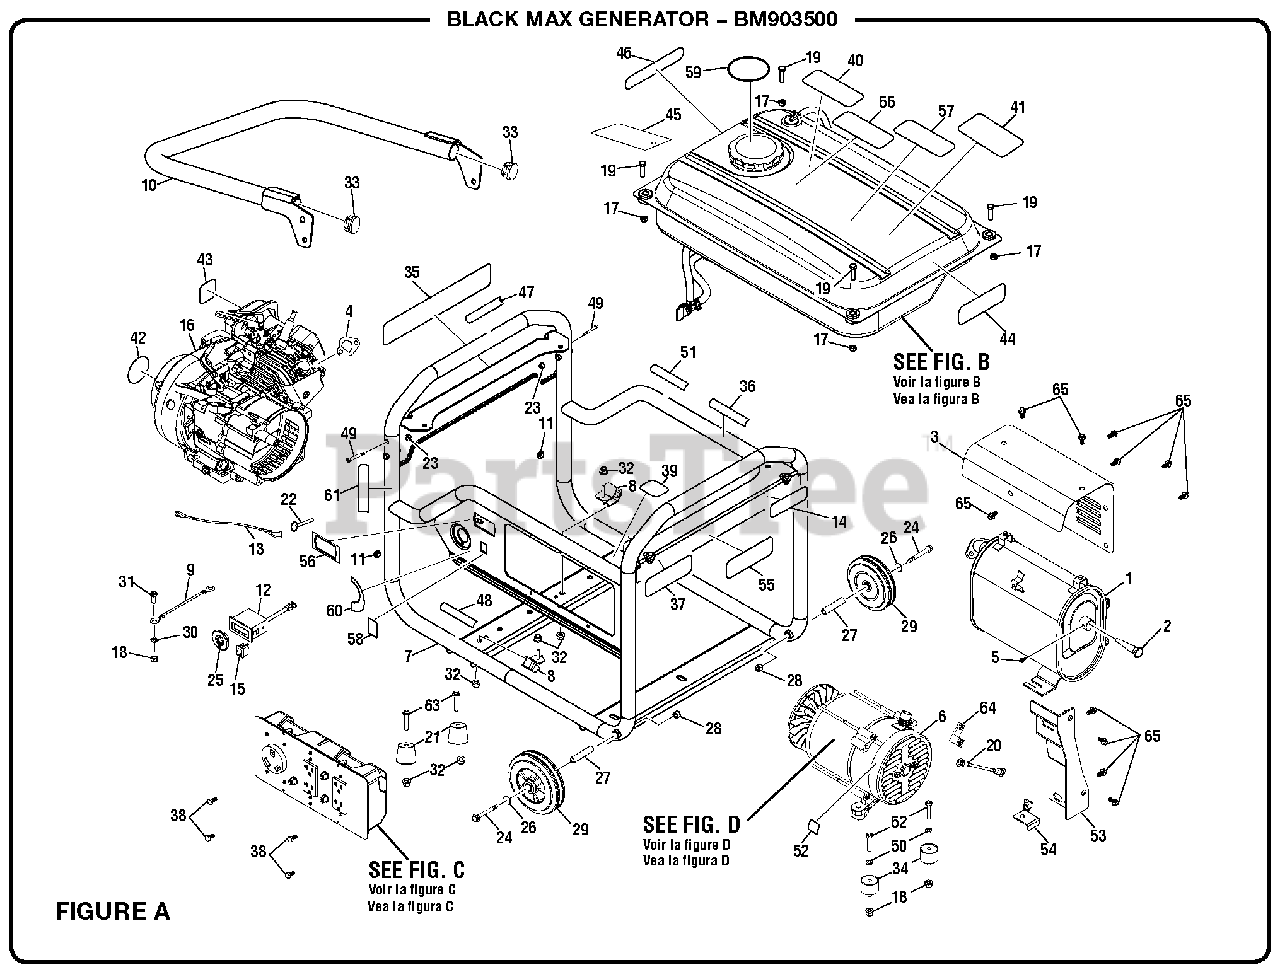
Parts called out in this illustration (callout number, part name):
2	Spark Screen
3	Heat Shield
4	Exhaust Gasket
5	Set Screw (Spark Arrestor)
6	Generator Head Assembly
7	Carrier Assembly
8	Isolators (45deg)
9	Ground Wire Assembly
10	Handle Assembly
11	Handle Bumper
12	Digital Display
14	Fire Distance Label
15	On/Off Switch
17	Lock Nut (M6)
18	Lock Nut (5/16-18)
19	Bolt (M6 x 20 mm, Hex Hd.)
20	Bonding Wire
21	Foot Assembly
23	Lock Nut (1/4-20)
24	Bolt (3/8-16 x 4-1/4 in.)
25	Fuel Valve Bezel
26	Washer (3/8 in.)
28	Lock Nut (3/8-16)
29	Wheel (7 in.)
30	Star Washer (5/16 in.)
31	Bolt (5/16-18 x 19 mm)
32	Flange Nut (M8).
34	Isolator (Generator)
35	Logo Label
36	Hot Surface Label
37	Combustion Label (Eng/Sp)
38	Screw (#6-20 x 9.65 mm, Pan Hd.)
39	Data Label
40	E85 Label
41	CPSC Label
42	Recoil Housing Label
43	Choke Label
44	Ground Warning Label
45	Danger Hang Tag
46	Engine Start Label
47	Fire Danger Label
48	Lubricant Label
49	Bolt (1/4-20 x 1.5 in., Flange Hex Hd.)
50	Lock Washer (5/16 in.)
51	Inquiries Label.
52	Ground Label.
53	Mounting Bracket (Left)
54	Mounting Bracket (Right)
55	Mexico Support Label
56	Hour Meter Label
57	Icon Label.
58	On/Off Label..
59	Fuel Stabilizer Label (Eng)
60	Fuel Valve Label
61	Lock Pin Label
62	Bolt (5/16-18 x 1.5 in., Hex Hd.)
63	Bolt (M8 x 1.25 in., Flange Hex Hd.)
64	Ground Lug
65	Bolt (M8 x 1.25 in., Flange Hex Hd.)
66	Fuel Stabilizer Label (Sp)
